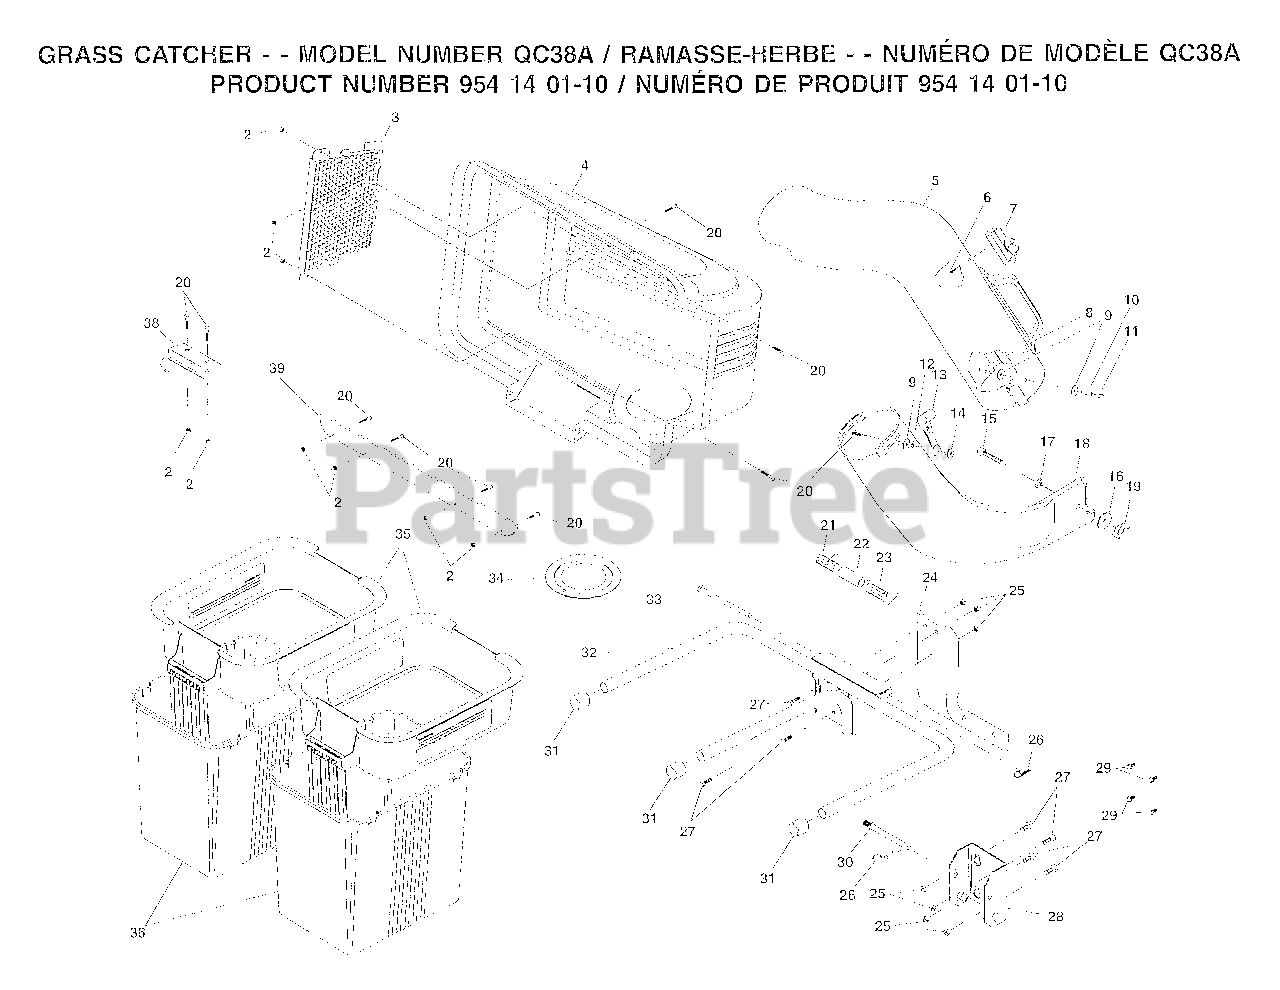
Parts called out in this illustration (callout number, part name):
6	SCREW, SPECIAL #10-14X1/2
9	WASHER 3/16X3/4X16 GA
16	WASHER
17	LOCKNUT
20	SCREW#10-24 X 5/8
27	BOLT, HEX 5/16-18 X 3/4
28	BRACKET, MOUNTING
29	BOLT SHOULDER
39	STRIP.REINFORCEMENT
